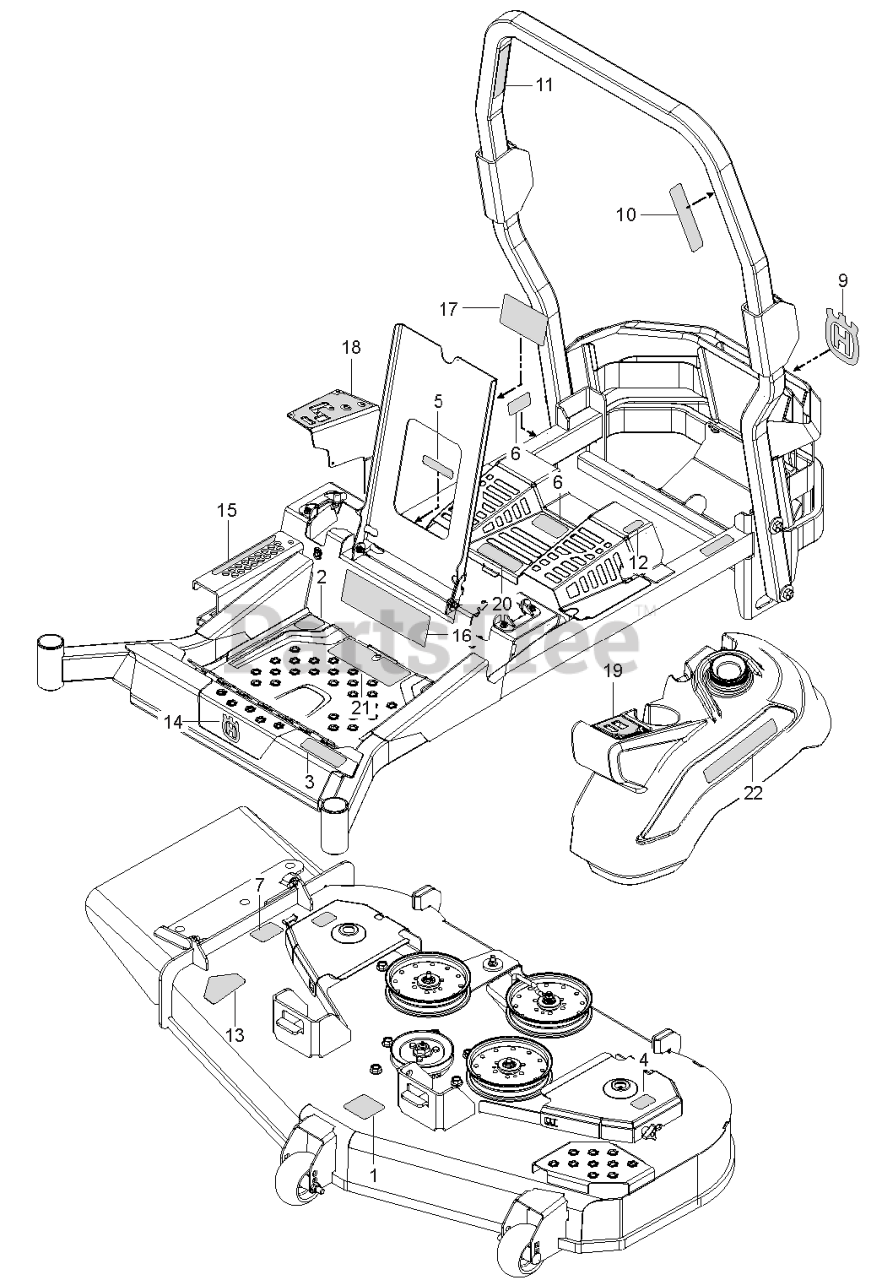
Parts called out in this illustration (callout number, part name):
1	DECAL, BELT ROUTING
2	DECAL.ZTR.SADLE.WARN.PZ500.ENG
3	DECAL.ZTR.PZ500SERIES.Z554X
4	DECAL.DECK.6MIL.EURO.NOSTEP
5	EURO DECAL-BATTERY WARNIN6
6	DECAL, BELT DRIVE
7	DECAL.DECK.6MIL./DEF.SHLD.WARN
9	DECAL, CROWN H, 110MM
10	DECAL ROPS DECAL DECAL.ROPS.PZ
11	DECAL, ROPS, WARNING
12	DECAL, FUSE
13	DECAL, DECK DEFLECTOR, WARNING
14	DECAL.BADGE.55MM.CROWNH.HUSQ
15	DECAL.PZ500.DECKLIFT.HUSQ
16	DECAL.ZTR.SADDLE.COMM.PZ500
17	DECAL.PZ500.MAINTANCE/SVC.2018
18	DECALZTR.CONTROLPANEL.PZ500.RH
19	DECAL.ZTR.CONTROLPANL.PZ500.LH
20	DECAL.ZTR.TRANCOVER.WARN.PZ500
21	DECAL.ZTR.SADLE.WARN.PZ500.ENG
22	DECAL.HUSQVARNA.210MM
